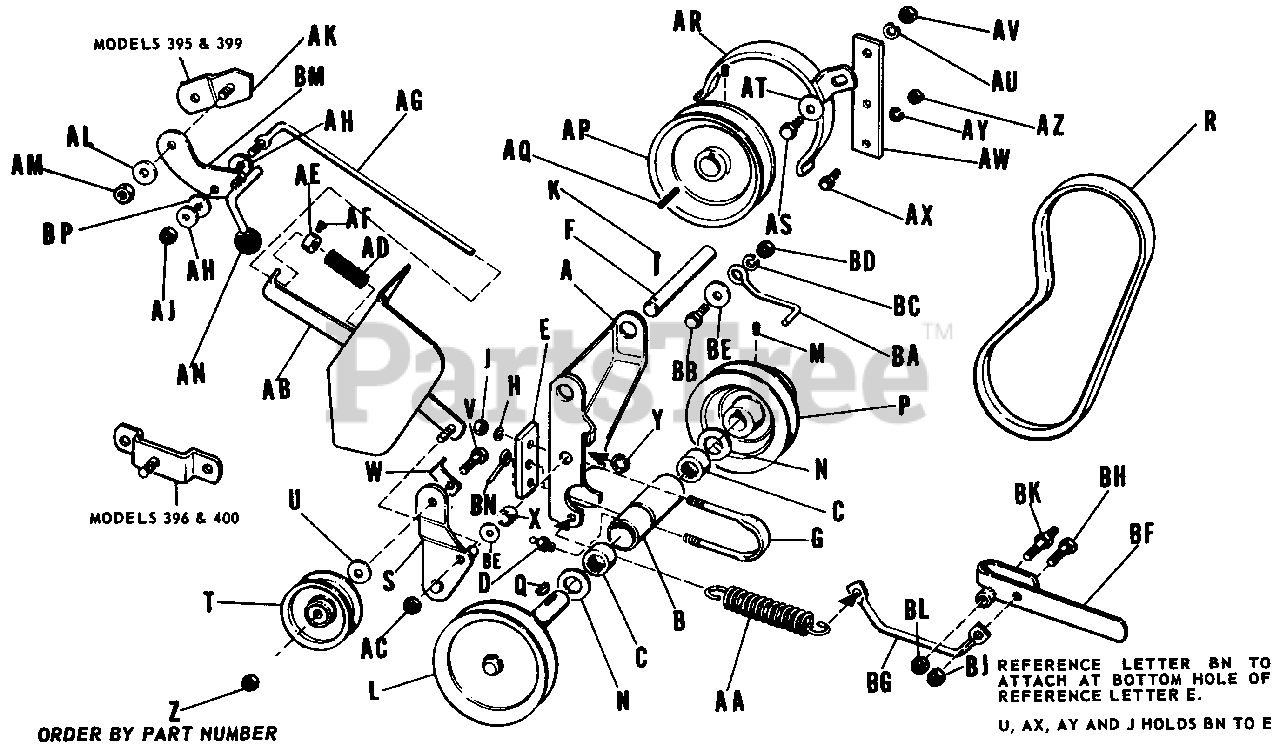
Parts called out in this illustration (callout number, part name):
A	P.T.O.-Bracket
B	Bearing Housing
C	Needle Bearing
D	Grease Fitting
E	Support Plate
F	Pivot Rod, 5/8" Dia. x 6-13/16"
H	Lock Washer, 5/16"
J	Full Hex. Nut 5/16"-18
K	Cotter Pin 3/16" Dia. x 1-1/2"
L	Shaft Assembly P.T.O.
M	Screw, Set, Skt. Hd. Cup Pt. 5/16"-18 x 5/16" Lg.
P	Pulley, P.T.O.
Q	Woodruff Key #9-3/16" x 3/4"
S	Idler Lever Assembly
T	Idler Pulley
U	Plain Washer 5/16"
V	Hex. Cap Screw, 3/8"-16 x 1-1/4"
Y	Retaining Ring
Z	Full Hex. Nut 3/8"-16
AA	Tension Spring
AB	Rod Guide Assembly
AC	Full Lock Hex. Nut, 3/8"-16
AF	Screw, Set Sq. Hd. Cup Pt., 1/4"-20 x 3/8" Lg.
AG	Clutch Rod Assembly
AH	Plain Washer 5/16"
AJ	Full Lock Hex. Nut 5/16"-18
AK	Pivot Bar Assembly
AL	Plain Washer 3/8"
AM	Full Lock Hex. Nut 3/8"-16
AR	Belt Guard Assembly
AS	Hex. Cap Screw, 3/8"-16 x 1"
AT	Plain Washer, 3/8"
AU	Lock Washer 3/8"
AV	Full Hex. Nut, 3/8"-16
AW	Belt Guard Support, 3/16" x 1-1/4" x 5-7/16" Lg.
AX	Hex. Cap Screw, 5/16"-18 x 1" Lg.
AY	Lock Washer, 5/16"
AZ	Full Hex. Nut, 5/16"-18
BA	Belt Stop
BB	Hex. Cap Screw, 3/8"-16 x 7/8"
BC	Lock Washer, 3/8"
BD	Full Hex. Nut, 3/8"-16
BE	Plain Washer, 3/8"
BF	Handle Assembly
BG	Spring Tension Rod
BH	Hex. Cap Screw, 5/16"-18 x 1-1/4"
BJ	Full Lock Hex. Nut, 5/16"-18
BL	Full Lock Hex. Nut, 7/16"-14
BM	Clutch Lever Assembly
BN	Belt Guide
BP	Special Washer
